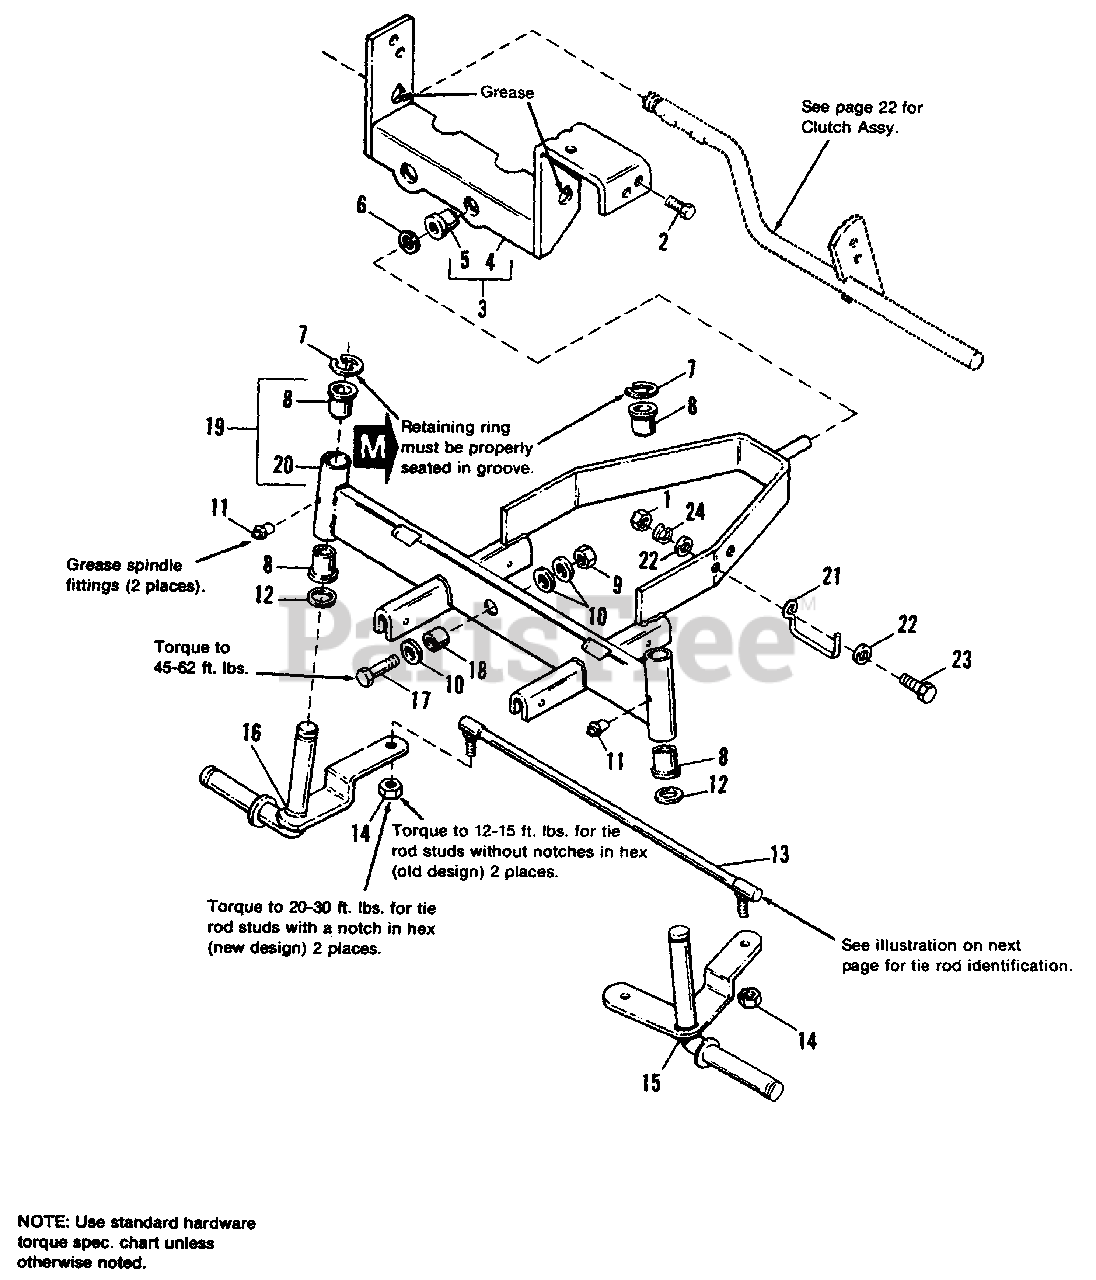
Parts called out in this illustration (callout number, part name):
1	NUT, Hex, 5/16-18
2	SCREW, Hex, Taptite, 5/16-18 x 3/4
3	SUPPORT ASSY., Axle, Rear w/Bushing (Incl. Ref. Nos. 4 & 5)
6	WASHER, 3/8
9	LOCKNUT, Hex, 1/2-13
10	WASHER, 9/16
11	FITTING, Grease
12	WASHER
13	ROD ASSY., Tie
14	LOCKNUT, Hex, 3/8-24
15	SPINDLE ASSY., L.H.
16	SPINDLE ASSY., R.H.
17	CAPSCREW, Hex Hd., 1/2-13 x 1-1/2
18	SPACER
19	AXLE ASSY., Front (Incl. Ref. Nos. 8 & 20)
21	GUIDE, Drag Link
22	WASHER, 5/16
23	CAPSCREW, Hex Hd., 5/16-18 x 1
24	LOCKWASHER, 5/16
